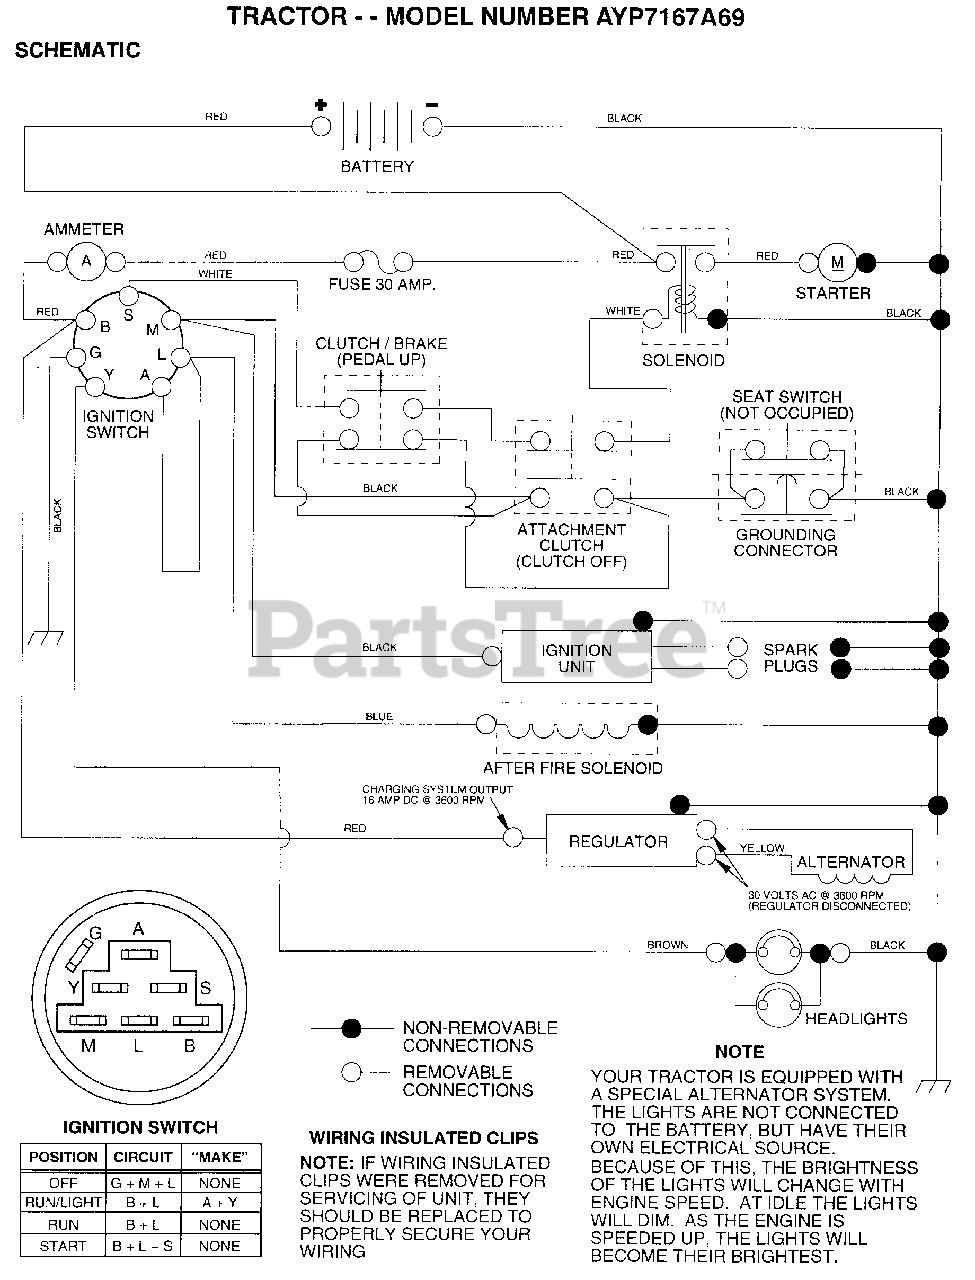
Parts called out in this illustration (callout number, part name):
2	BOLT LT
3	WASHER
4	LOCKWASHER
7	"DRAIN TU T, BATT"
8	"TRAY T, BATTERY"
9	HOSE CLAMP T
20	NUT
21	"HARNESS,LIGHT SOC"
22	HEADLAMP BULB
24	"CABLE T, BATTERY"
25	CABLE.6GA.22W/16W
26	FUSE HYT
28	CABLE.GRND.6GA.21
29	SWITCH SEAT
30	SWITCH IGN 4POS
31	NUT IGNITION
32	COVER KEY SWITCH
33	KEY
35	BRACKET LT
36	SCREW
38	BRACKET SWITCH IN
39	SWITCH INTERLOCKT
40	HARNESS.IGNITION
41	BOLT HXHD FIN
44	NUT HXKEP 1/4X20
45	AMMETER
52	PROTECTION LOOP
55	SCREW LT
70	HARNESS.ENG.LT.
